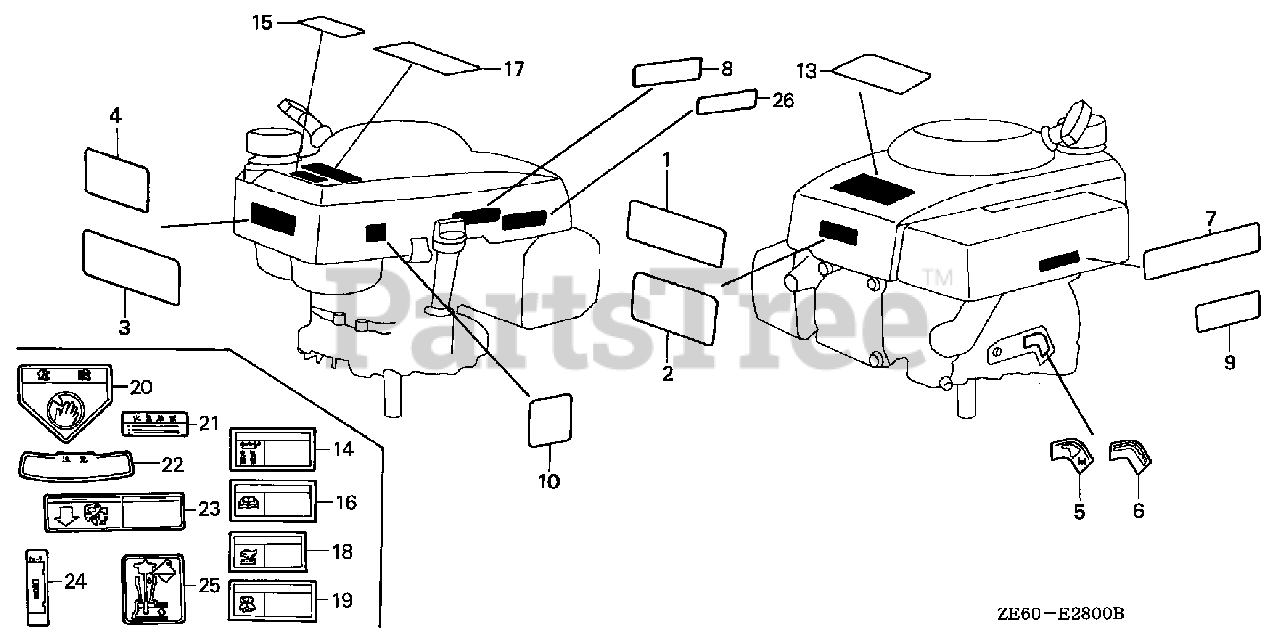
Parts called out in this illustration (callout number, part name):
2	MARK, TOP COVER
3	MARK, CAUTION
6	MARK, CONTROL
7	MARK, AIR CLEANER CAUTION
8	MARK, BRAKE CAUTION
